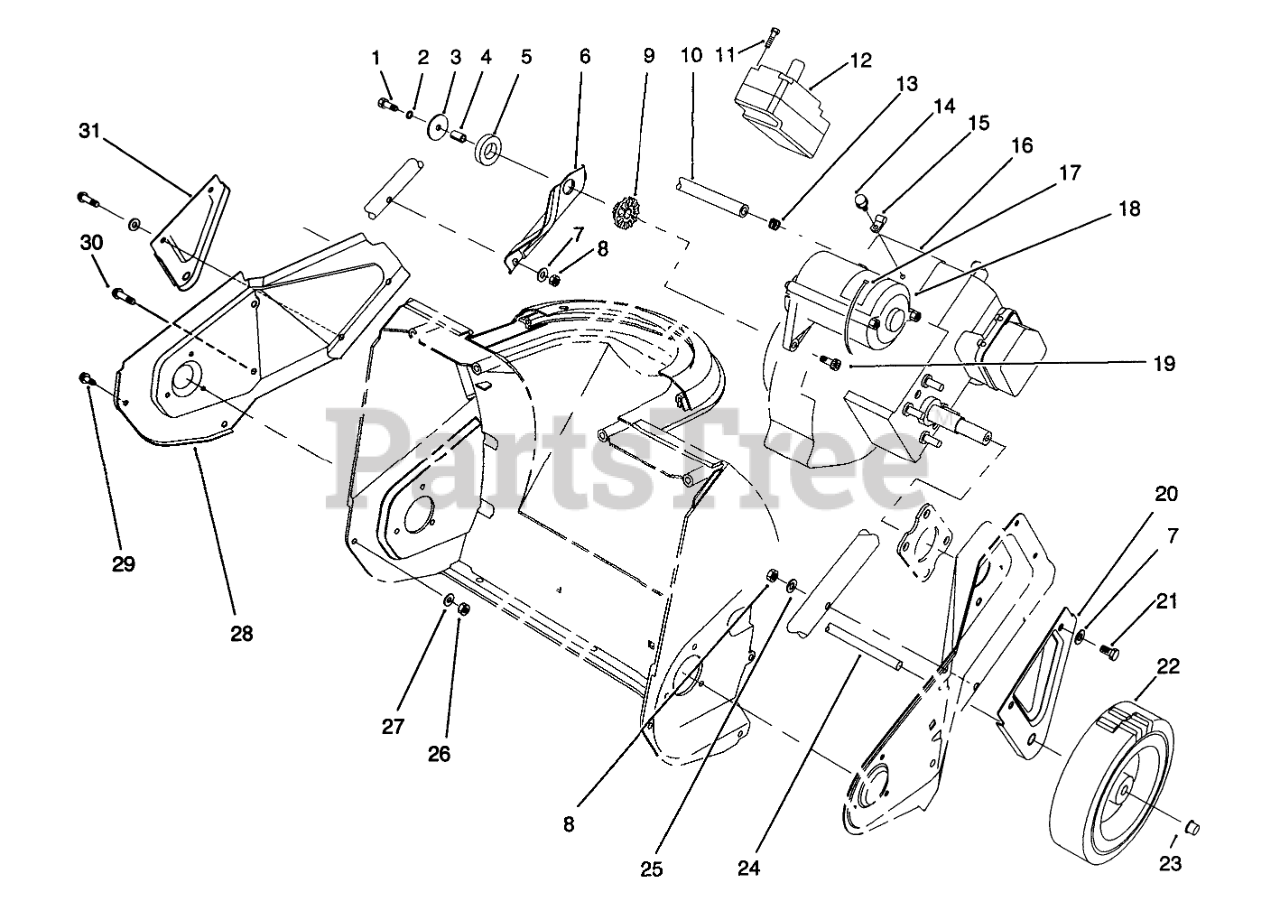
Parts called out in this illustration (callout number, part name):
1	SCREW-HH
2	WASHER-LOCK
3	WASHER-FLAT
4	SPACER-TUBULAR
5	Ring-Isolator
6	Support-Engine
7	WASHER-FLAT
8	NUT-LOCK, NI
9	BUSHING-ISOLATOR
10	LINE-GAS
11	SCREW-PLASTITE
12	Motor Switch Housing Ass-y (Model No. 38175 Only)
13	Clamp
14	SCREW-HWH
15	CLAMP
17	TIE-CABLE
18	Starter Motor Assembly
19	Screw-Thread Forming
20	Bracket-Wheel
21	SCREW-HH
22	WHEEL
23	RETAINER-PUSH ON
25	WASHER
26	NUT-LOCK, NI
27	WASHER-FLAT
28	Sideplate-RH
30	SCREW-PLASTIC
31	Bracket-Wheel
